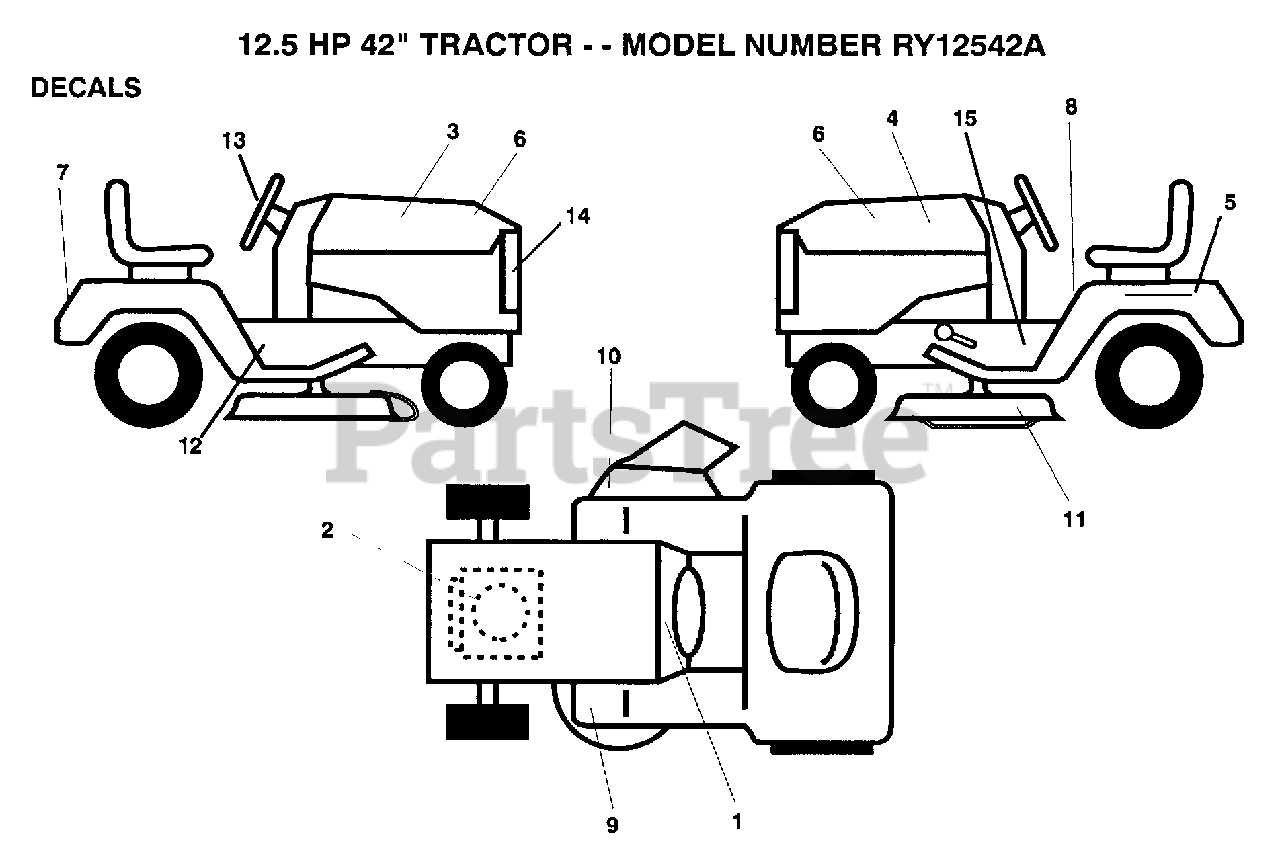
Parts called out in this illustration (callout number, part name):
4	DECAL HOOD LH
5	DECAL
6	DECAL HP HOOD
7	FENDER DECAL
8	DECAL CAUTION
9	DECAL T
10	DECAL WARNING
11	DECAL YT
12	CHASSIS DECAL
13	"DECAL,STR WHL"
14	DECAL GRILL
